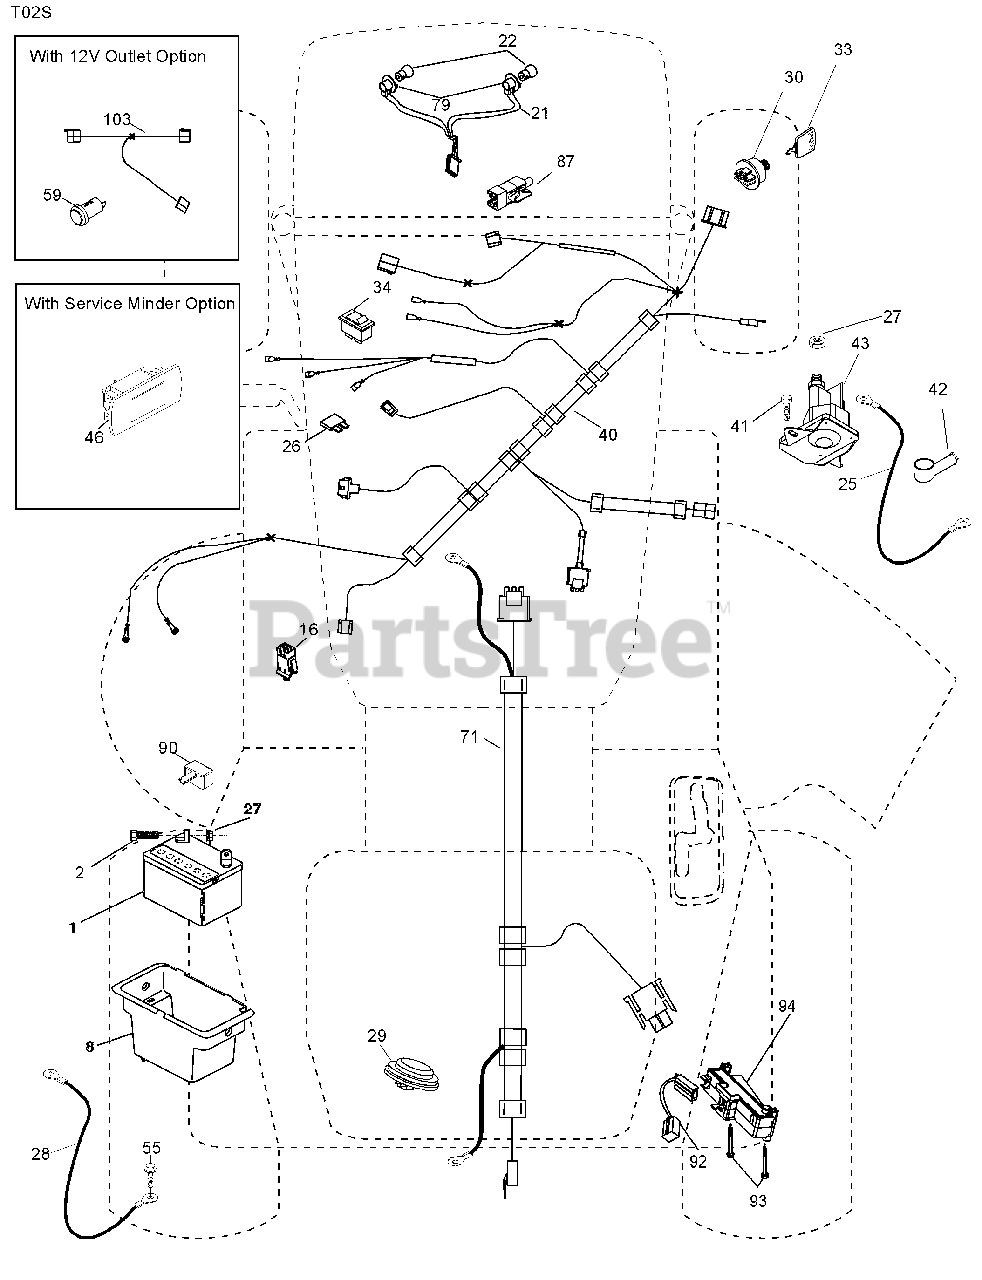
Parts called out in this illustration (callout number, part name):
1	Battery
2	Bolt Hex Head 1/4-20 x 3/4
8	Box Battery
16	Switch Interlock Push-In
21	Harness Socket Light w/4152J
22	Bulb Light
25	Cable Starter
27	Nut Keps Hex 1/4-20 unc
28	Cable, Ground
29	Switch, Seat
30	Switch, Ign
33	Key, Ignition
34	Switch Light / Reset
40	Harness Ign. Dash
41	Screw Thd Cut 1/4-20 x 1/2
42	Cover, Terminal
43	Solenoid
55	Screw Thdrol 5/16-18 x 3/4
71	Harness Chassis
79	Socket Asm Bulb Twistlock
87	Switch Interlock Clutch Cable
90	Cover, Terminal Battery
92	Harness Pigtail Reverse Switch
93	Screw Plastite 10-14 x 2.0
94	Module Reverse ROS
